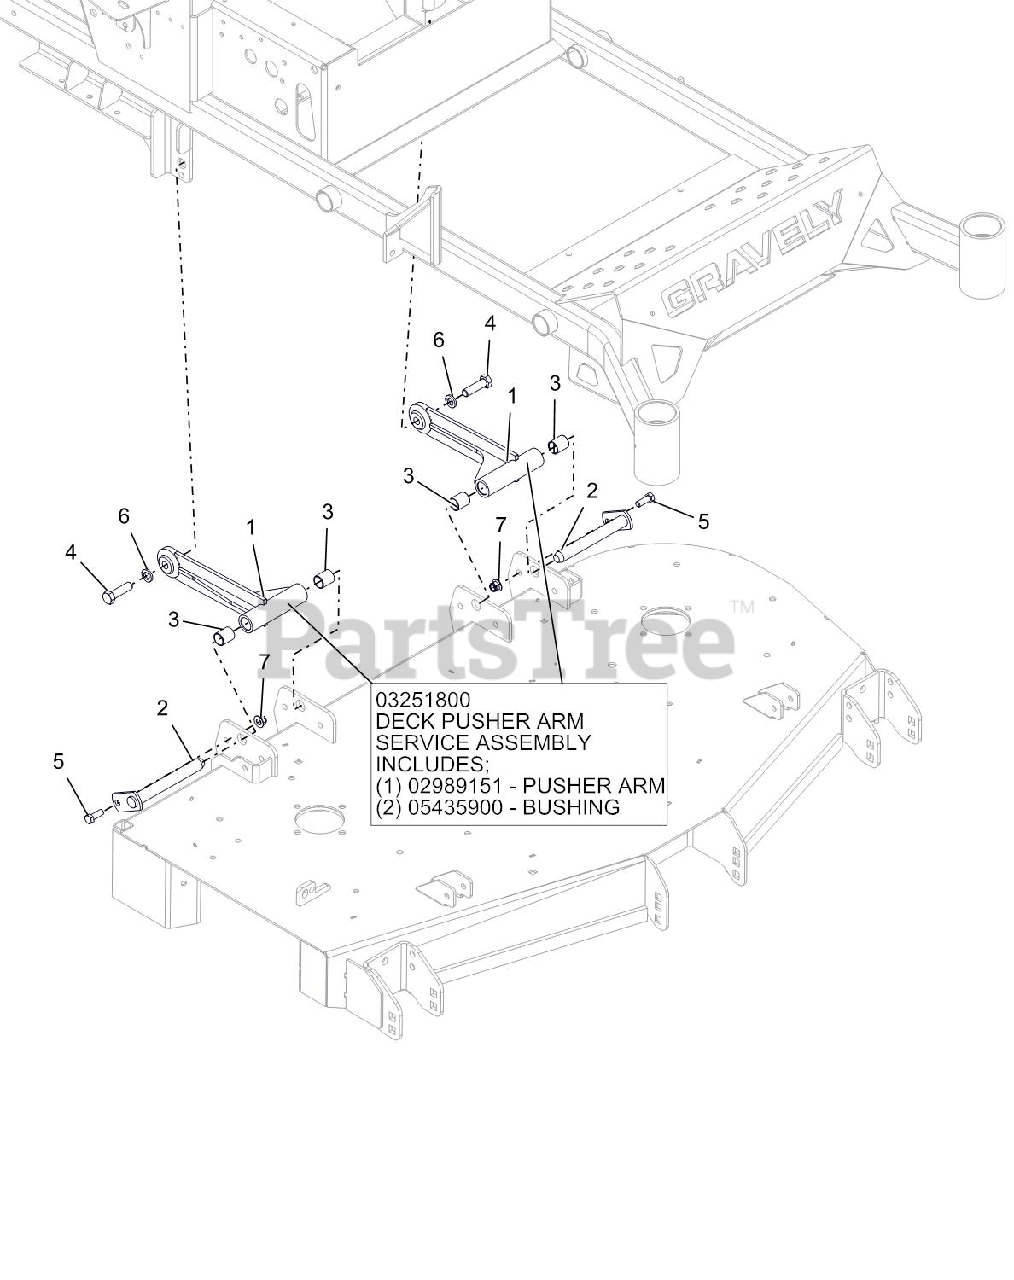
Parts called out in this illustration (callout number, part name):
1	BRG, .750 X .875 X 1.000
1	DECK PUSHER ARM WMT - BLACK
1	DECK PUSHER ARM ASSEMBLY
2	WELDMENT, MOWER MTG. PIN
3	BRG, .750 X .875 X 1.000
4	BLT-HEX .50-13X1.75 GR5EP80 YZ
5	@BLT-HEX .38-16X1.00 GR5 YWZC
6	@WSHR-LK .50X.125 REG YWZC
7	@NUT-LK-NYL-FLG .38-16 YWZC
